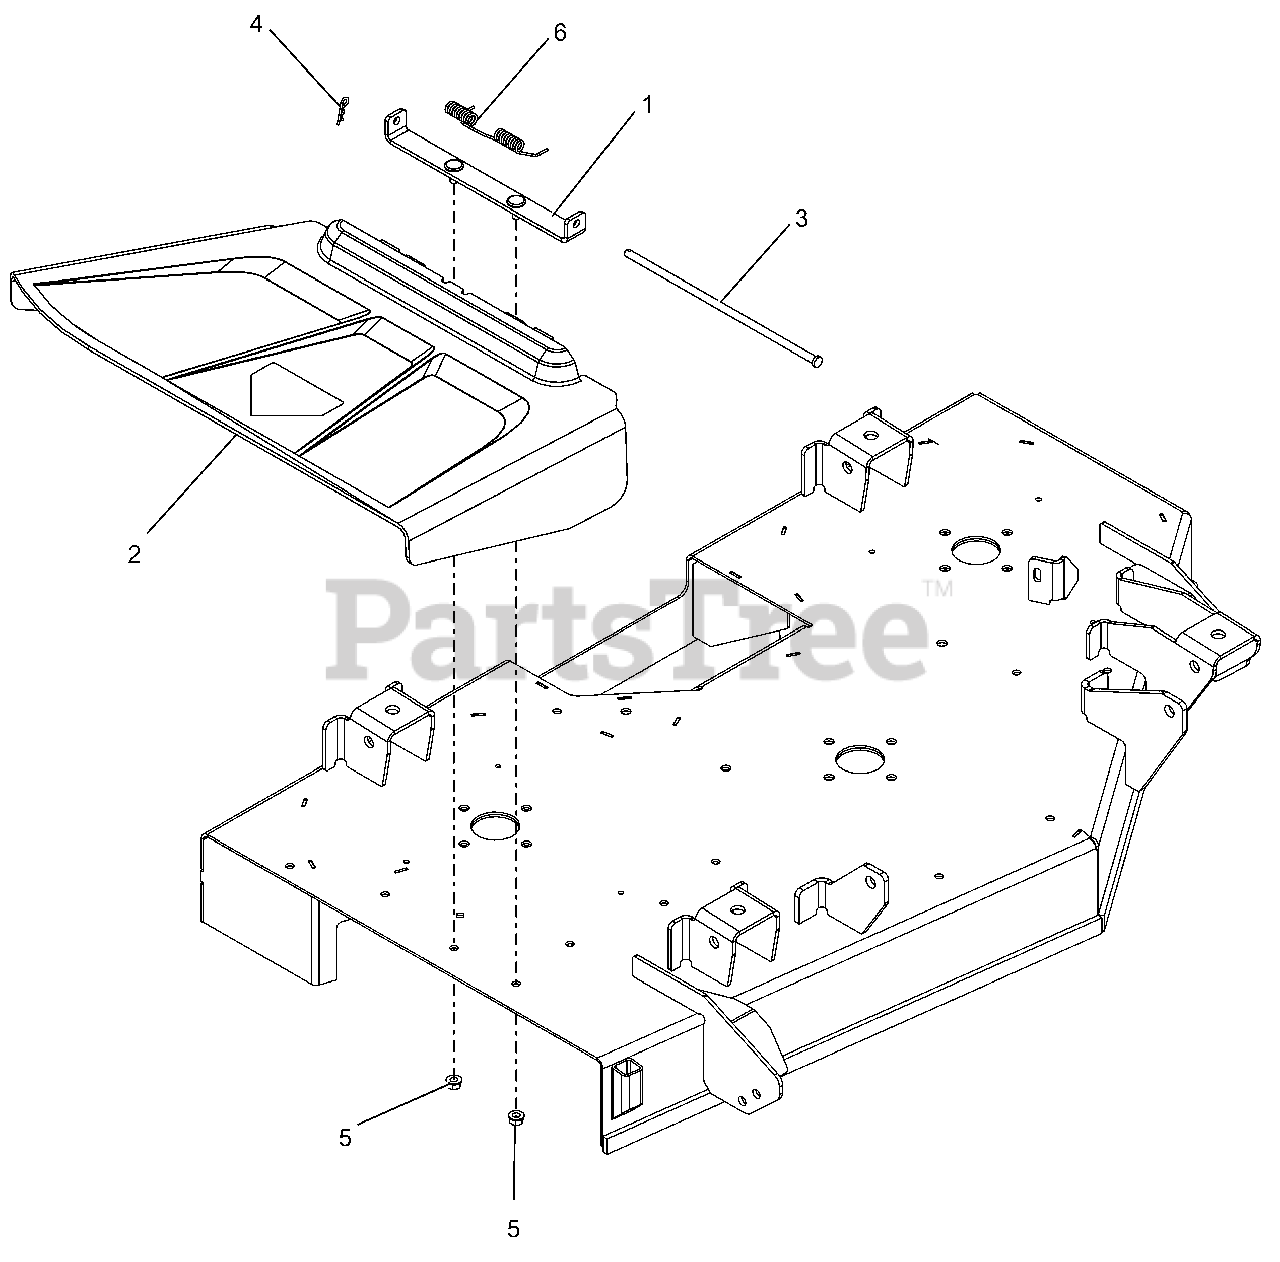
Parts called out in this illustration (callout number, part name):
2	CHUTE, SIDE DISCHARGE
3	PIN, 5/16 X 10.5
4	PIN, HAIR #213 .08X1.19 ZCC
5	NUT-LK-TOP-FLG .312-18 GF ZCC
6	SPRING-TORSION
